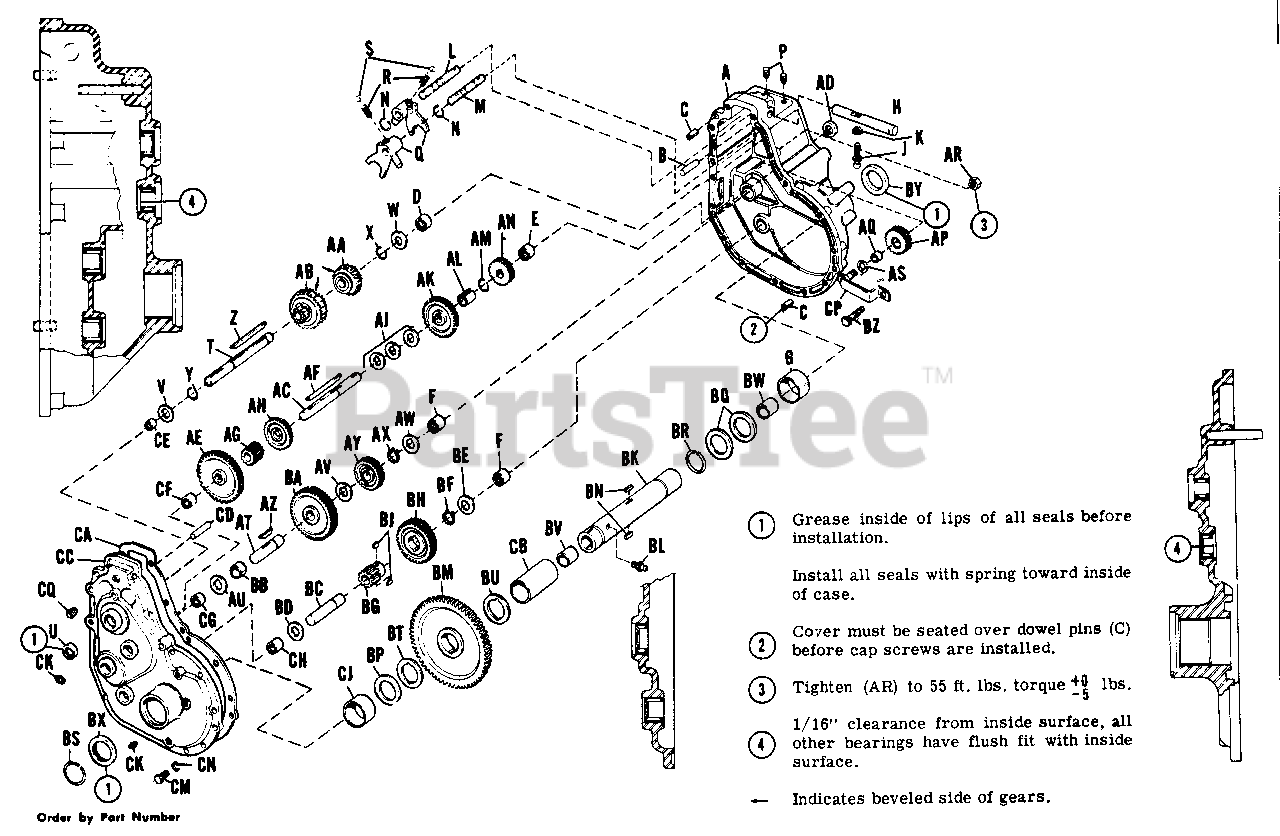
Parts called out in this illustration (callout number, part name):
A	Case, Gear, Complete w/ bearings and dowel pins
B	Pin, Roll
C	Pin, Roll
D	Bearing, Needle
E	Bearing, Needle
F	Bearing, Needle
G	Bearing, Axle Tube
H	Rod, Shift
J	Stem, Shift
K	Nut, Hex., Full, 3/8"-24 N.F.
L	Shaft, Shifter, Rev., Med. V
M	Shaft, Shifter, High, Low
N	Ring, Retaining
P	Screw, Set, Hollow Head, Cone Point, 5/16"-18 N.C. x 12" lg.
Q	Fork, Shift
S	Ball, Shift Lock
T	Shaft, Pulley
X	Ring, Retaining
Y	Ring, Retaining
AA	Pinion Assembly, Rev., II
AB	Pinion Assembly, I and III
AC	Shaft, 1st Intm.
AE	Gear, Driven, I
AG	Pinion, 1st Intm.
AH	Pinion, Driven, III
AJ	Spacer, Trans. Gear
AK	Gear, Driven, II
AM	Ring, Retaining
AN	Pinion, Reverse
AP	Gear, Reverse
AQ	Spacer, Rev. Gear
AR	Nut, Lock, 1/2"-20 N.F.
AT	Shaft, 2nd. Intm.
AX	Ring, Retaining
AY	Pinion, 2nd. Intm.
BA	Gear, 2nd. Intm.
BC	Shaft, 3rd. Intm.
BF	Ring, Retaining
BG	Pinion, 3rd. Intm.
BH	Gear, 3rd. Intm.
BJ	Key, Woodruff
BK	Tube Axle
BL	Fitting, Grease
BM	Gear, Drive
BT	Washer, Axle Tube
BU	Washer, Axle Tube
BZ	Screw, Cap, Hex, 3/8"-16 N.C. x 1-1/4" lg.
CA	Gasket, Gear Case
CB	Spacer, Axle Tube
CC	Cover, Gear Case, Complete w/ bearings
CD	Pin, Roll
CE	Bearing, Needle
CF	Bearing, Needle
CG	Bearing, Needle
CH	Bearing, Needle
CJ	Bearing, Axle Tube
CK	Plug, Pipe, 3/8"
CM	Screw, Cap, Hex., 5/16"-18 N.C. x 1" lg.
CN	Washer, Lock, 5/16"
CP	Pin Assembly, Rev. Gear
CQ	Plug, Pipe, 3/8"
